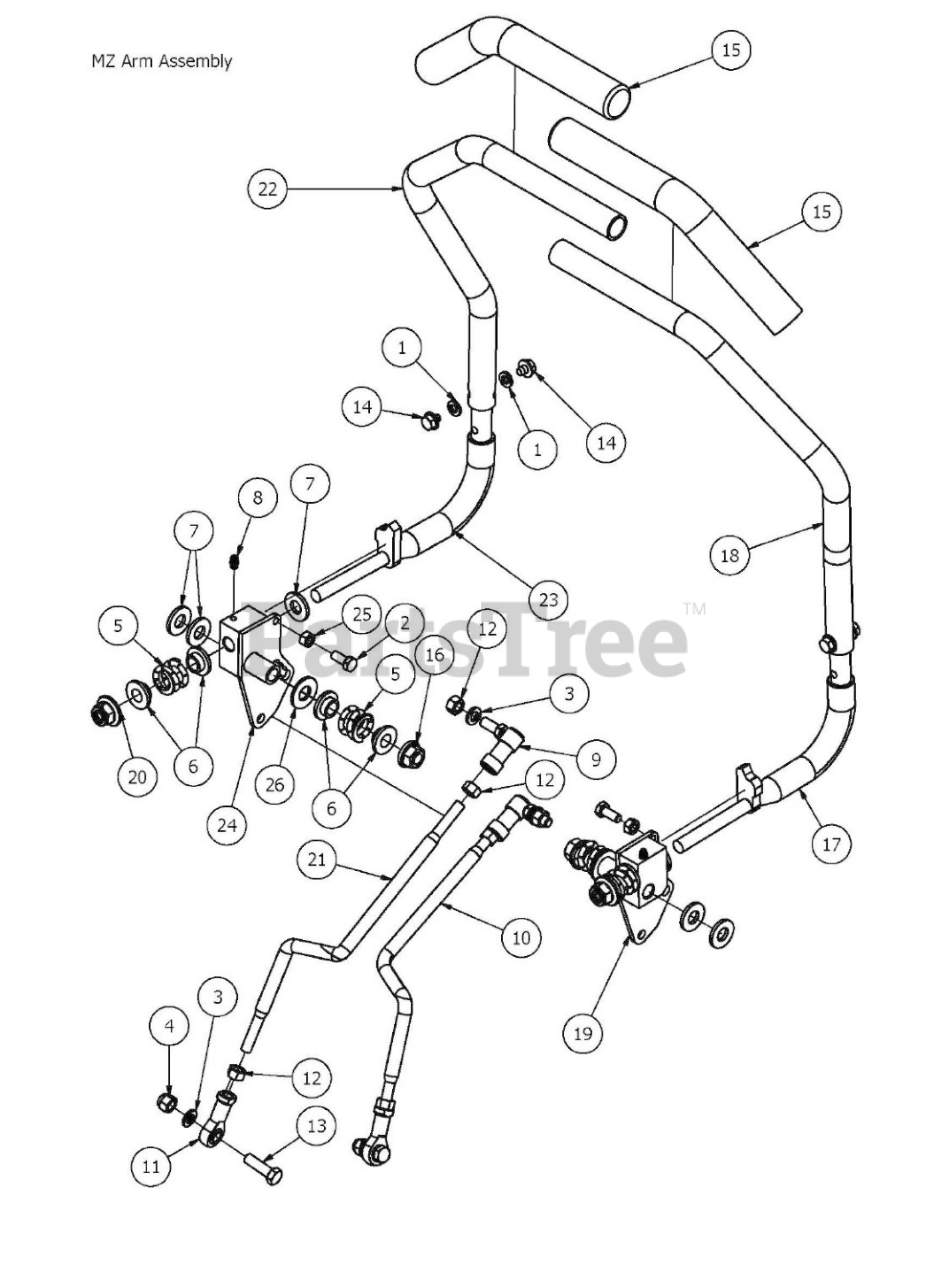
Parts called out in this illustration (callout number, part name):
1	5/16" Lock Washer
2	5/16" x 3/4" Hex Bolt
3	3/8" Lock Washer
4	3/8 Nylock Nut
5	Drive Lever Spring
6	.515 ID Nylon Shoulder Washer
7	.505 Nylon Spacer
8	1/4 Drive-In Grease Fitting
9	3/8-24 Quick Release Ball Joint
10	Push Rod - Right
11	Spherical Rod End - Outlaw
12	3/8" Fine Threaded Jam Nut
13	3/8" x 1 1/4" Hex Bolt
14	5/16-18 1/2 HWH Bolt-Steering
15	Rubber Grip
16	1/2-13 Hex Flange (GR.G) ZC
17	Steering Arm Elbow - Right
18	ZT Direction Steering Arm (Right)
19	2017 Drive Lever Housing - Right
20	1/2-13 Nylon Flange Nut
21	Push Rod Left
22	ZT Direction Steering Arm (Left)
23	Steering Arm Elbow - Left
24	2017 Drive Lever Housing - Left
26	1/2" Washer (Grade 8)
